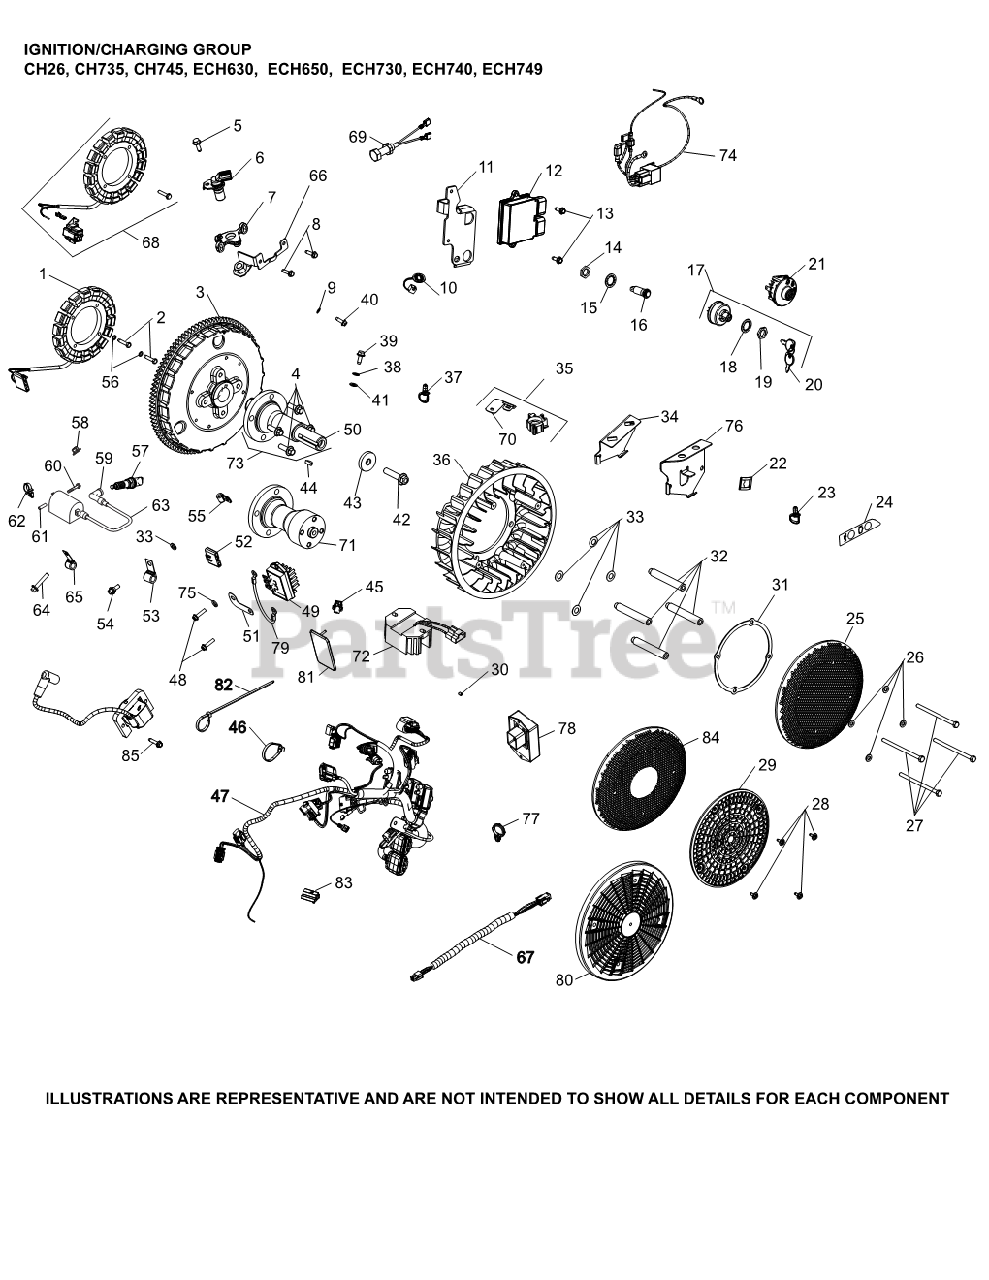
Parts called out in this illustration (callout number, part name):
1	KIT, 15 / 20 AMP STATOR
2	SCREW, M5X0.8X25 - (#25086402S)
3	FLYWHEEL ASSEMBLY
5	SCREW,FLG THD FRM M6X1.0X20-(#25086396S)
6	SENSOR, SPEED
7	BRACKET, SENSOR MOUNT-(#2512616S)
8	SCREW,FLG THD FRM M5X0.8X16-(#25086398S)
9	WASHER, INT TOOTH LOCK #10
10	CAP, CONNECTOR
11	BRACKET, ECU USE 24 126 197-S
12	MODULE, ECU
16	LAMP, INDICATOR (INCANDESCENT)
18	WASHER, INTERNAL TOOTH
19	NUT, KEY SWITCH
20	KEY, SET OF 2
21	KIT, KEY SWITCH (SNAP-IN)
23	TIE, WIRE
24	DECAL, WARNING LIGHT
25	KIT, GRASS SCREEN
28	SCREW, FLG SEMS M4X.7X25
30	SCREW, FLG M10X1.5X45 - (#25086361S)
35	KIT, MOUNTING CLIP
36	FAN USE 24 755 253-S
38	WASHER, INT TOOTH LOCK 1/4"
41	WASHER, FLAT 1/4" (O.D. 1/2")
43	WASHER, FLAT 13/32"
44	KEY, 3/16" X 5/8"
47	HARNESS, WIRING ASSEMBLY
48	SCREW, HEX FLANGE HI-LO
49	REGULATOR, RECTIFIER USE 25 403 32-S
51	BRACKET, GROUND STRAP USE 24 518 12-S
53	CLIP, CABLE
54	BOLT, SHOULDER
56	WASHER, FLAT 3/16"
57	PLUG, SPARK (PRO SERIES)
63	COIL, IGNITION-EFI - USE 25 519 02-S
64	SCREW, FLG M6X1.0X34
65	CLIP, CABLE
